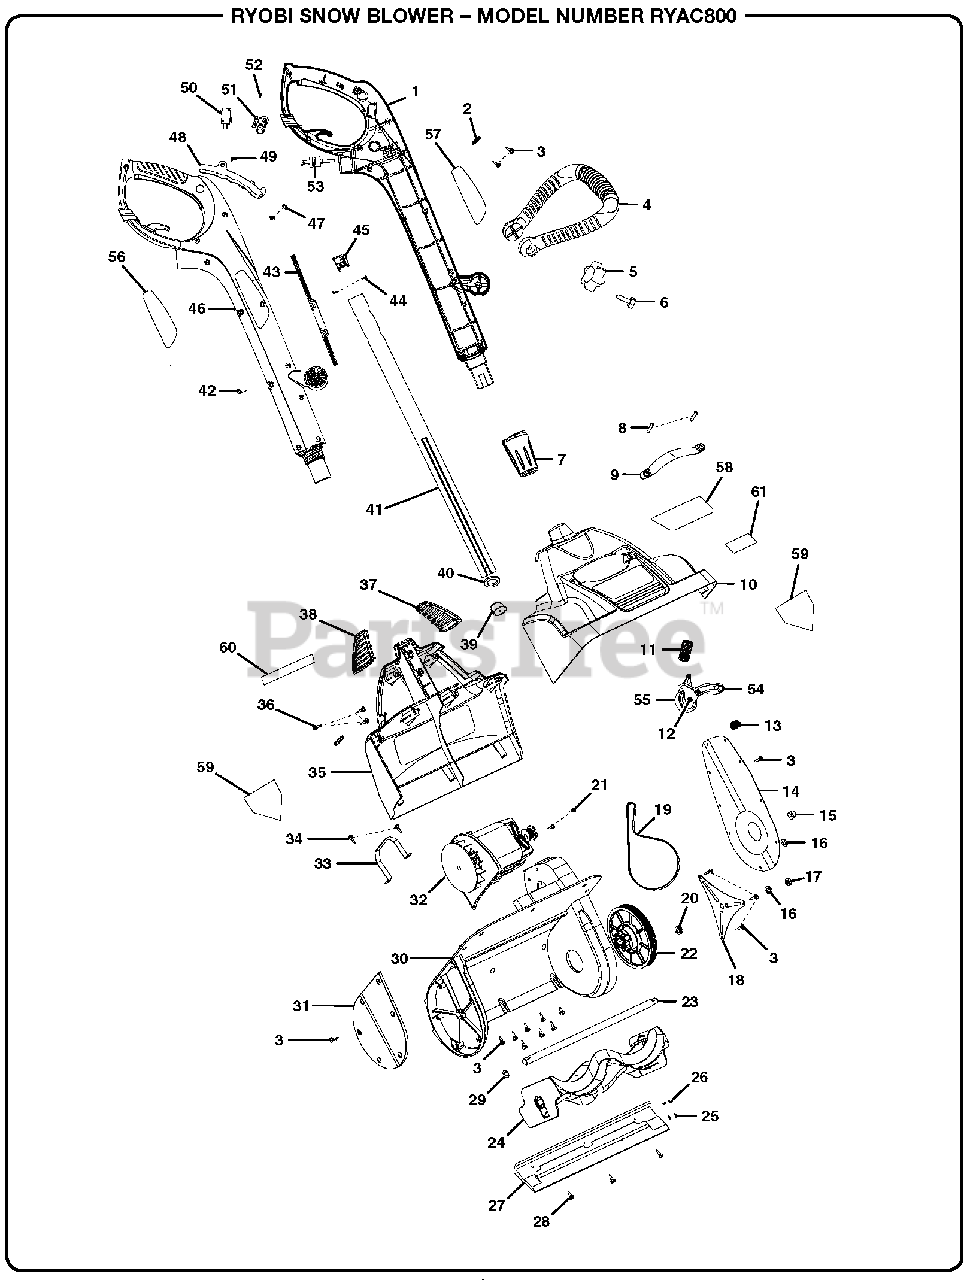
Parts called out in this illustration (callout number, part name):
1	Left Handle
3	Screw (M4 x 15 mm)
4	Auxiliary Handle
8	Screw (M6 x 25 mm)
10	Front Housing (Upper)
12	Board (Tension Wheel)
16	Washer (M10)
18	Pulley Bracket
20	Washer (M13)
21	Screw (M5 x 18 mm)
22	Belt Pulley
25	Screw (M4 x 12 mm)
26	Washer (M4)
28	Screw (M4 x 13 mm)
29	Washer (M4)
30	Lower Housing
31	Right Cover
32	Motor Assembly
33	Motor Bracket
34	Screw (M48 x 15 mm)
35	Upper Back Housing
36	Screw (M4 x 18 mm)
37	Left Venting
38	Right Venting
39	Bend Relief
40	Washer (Rubber)
42	Screw (M4 x 10 mm)
44	Screw (M35 x 8 mm)
46	Right Handle
47	Terminal (B)
51	Lockout Button
52	Lockout Spring
54	Bracket (Tension Wheel)
56	Logo Label (Left)
57	Logo Label (Right)
58	Performance/Logo Label
59	Danger Label (No Hands/Feet)
60	Data/Warning Label
61	Chute Icon Label
